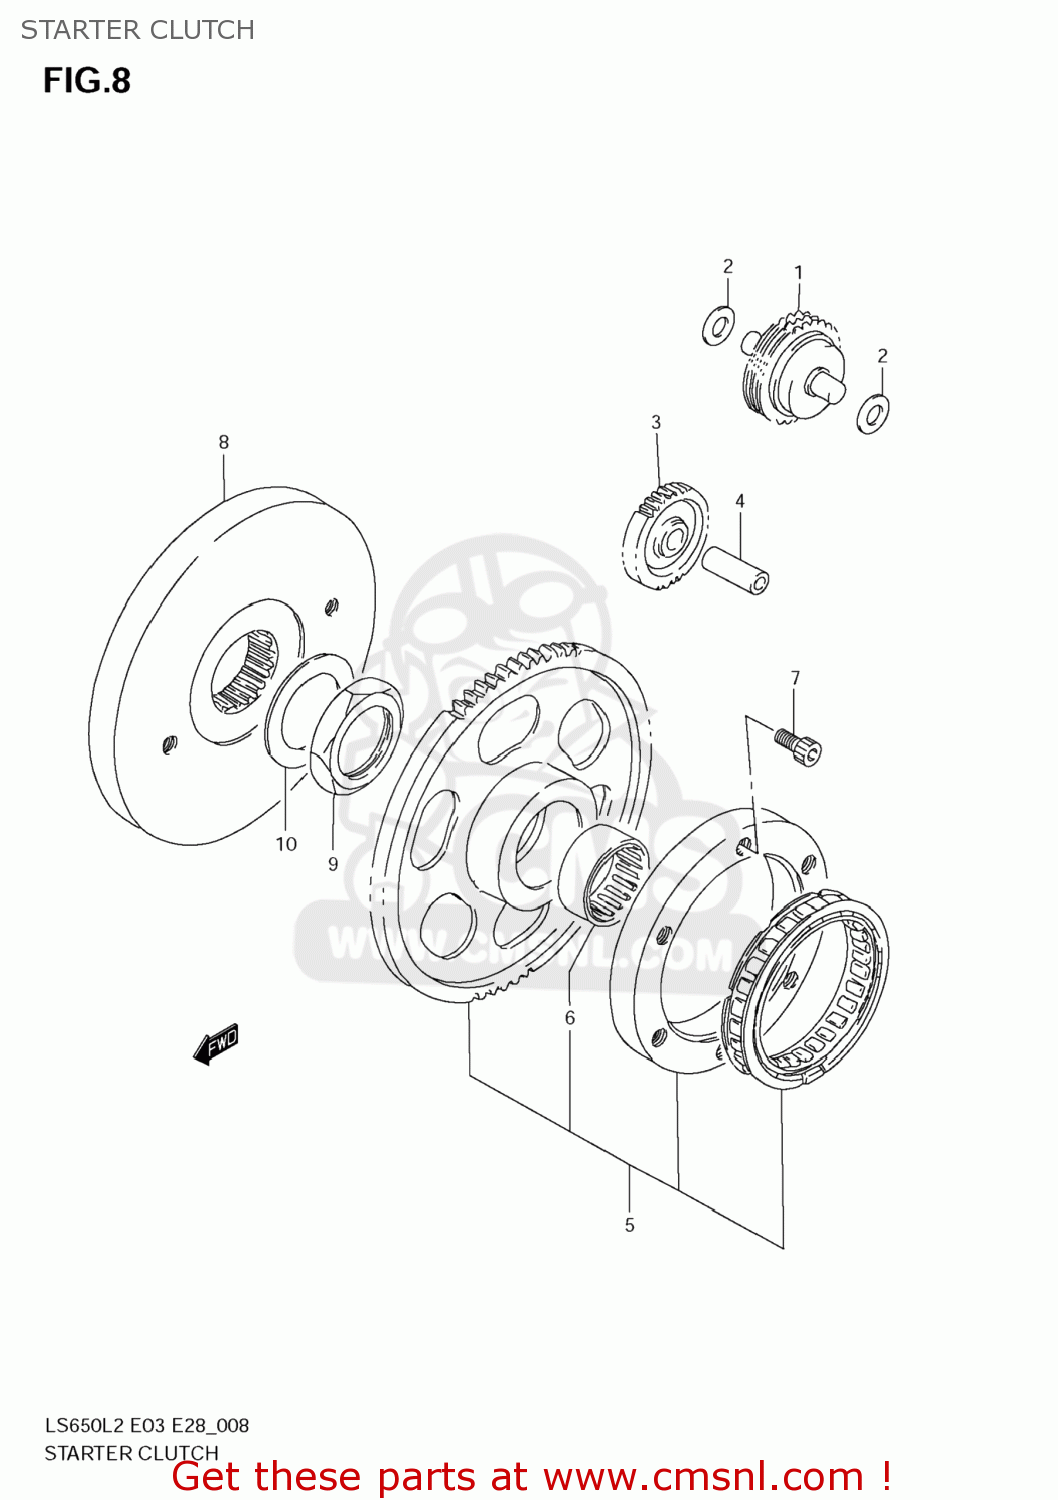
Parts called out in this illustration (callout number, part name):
1	LIMITER ASSY,START ID GR NO.1
2	SHIM(10X18X1)
3	GEAR,STARTER IDLE NO.2
4	PIN(10X30)
5	CLUTCH SET,STARTER
6	BEARING(31X39X17.8)
7	BOLT(8X16)
8	FLYWHEEL
9	NUT,FLYWHEEL
10	WASHER
